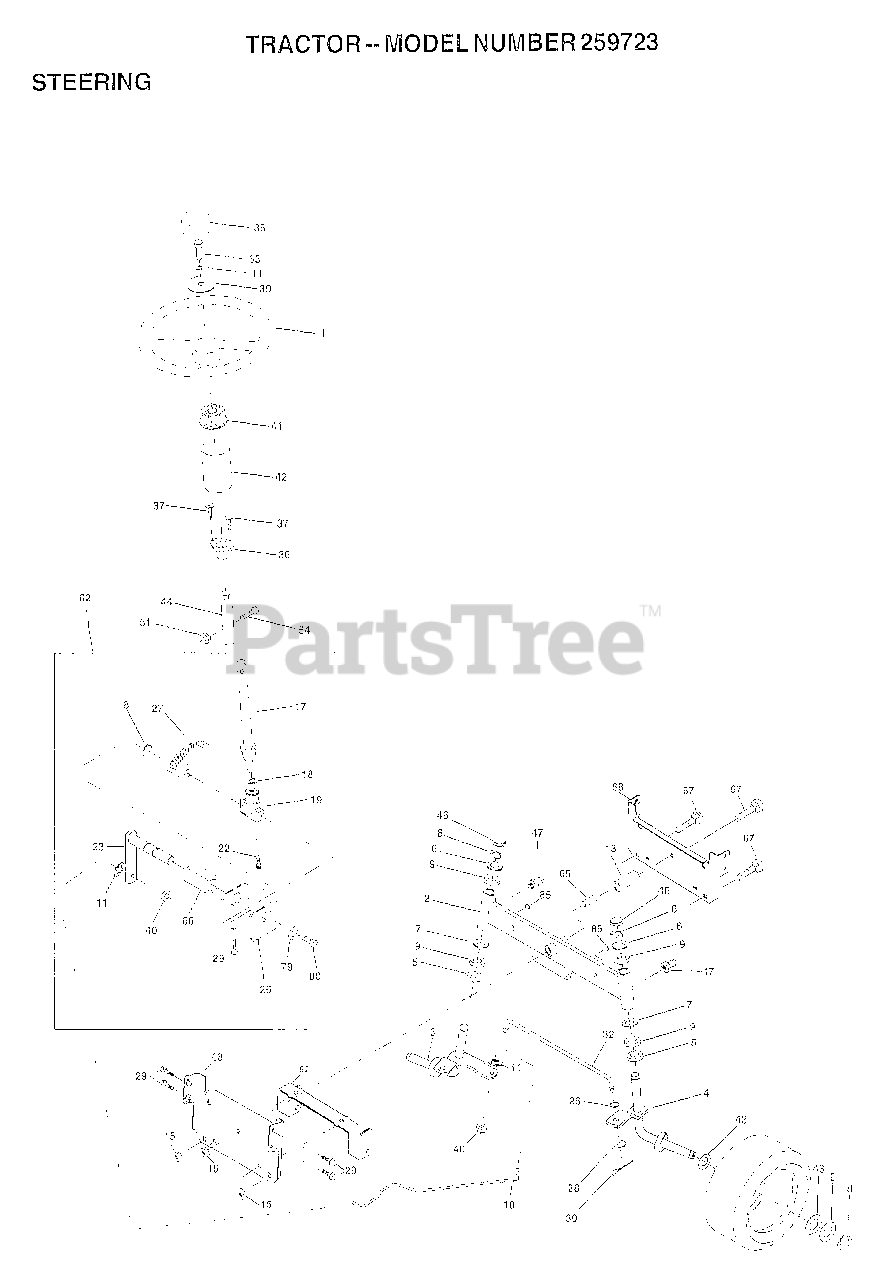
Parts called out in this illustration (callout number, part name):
1	WHEEL STR AYP BLK
2	AXLE ASM
3	SPINDLE.ASM.LH
4	"SPINDLE ASM,RH"
5	WASHER .T
6	WASHER
7	WASHER
8	RING
9	COL. SRTG. BEAR.
10	LINK DRAG
11	LOCKWASHER
13	SPACER BEARING
15	NUT.HXFLG.LOCK.
17	SHAFT ASM STEERIN
18	THRUST WASHER
19	SUPPORT.SHAFT.STEER
22	SCREW.HX.WSH.HD
23	SHAFT.ASM.PITMAN
25	BRKT-STEERING
26	BUSHING.DRAGLINK
27	GEAR SECTOR
28	WASHER
29	SCREW
30	COTTER PIN
32	TIE ROD
36	BUSHING.STEERING
37	"SCREW-TT,10-32 FL"
38	CAP STEER AYP
39	WASHER
40	GRIPCO NUT
41	ADAPTER LT
42	BOOT.STEERING.DASH.P/L
43	WASHER
44	EXT SHAFT STEERIN
46	CAP
47	ZERK M
51	NUT
54	BOLT
62	KIT.STEER.ASM
63	BOLT
65	"SPACER BRCAE,AXLE"
66	"BEARING-ARM,PITMA"
67	BOLT RDHD 3/8-16
68	BRACE AXLE
79	WASHER
80	BOLT.HX.NYLON3/8-16X3/
82	BRKT SUSP CHASSIS FRT
85	XMAS TREE FASTNER
